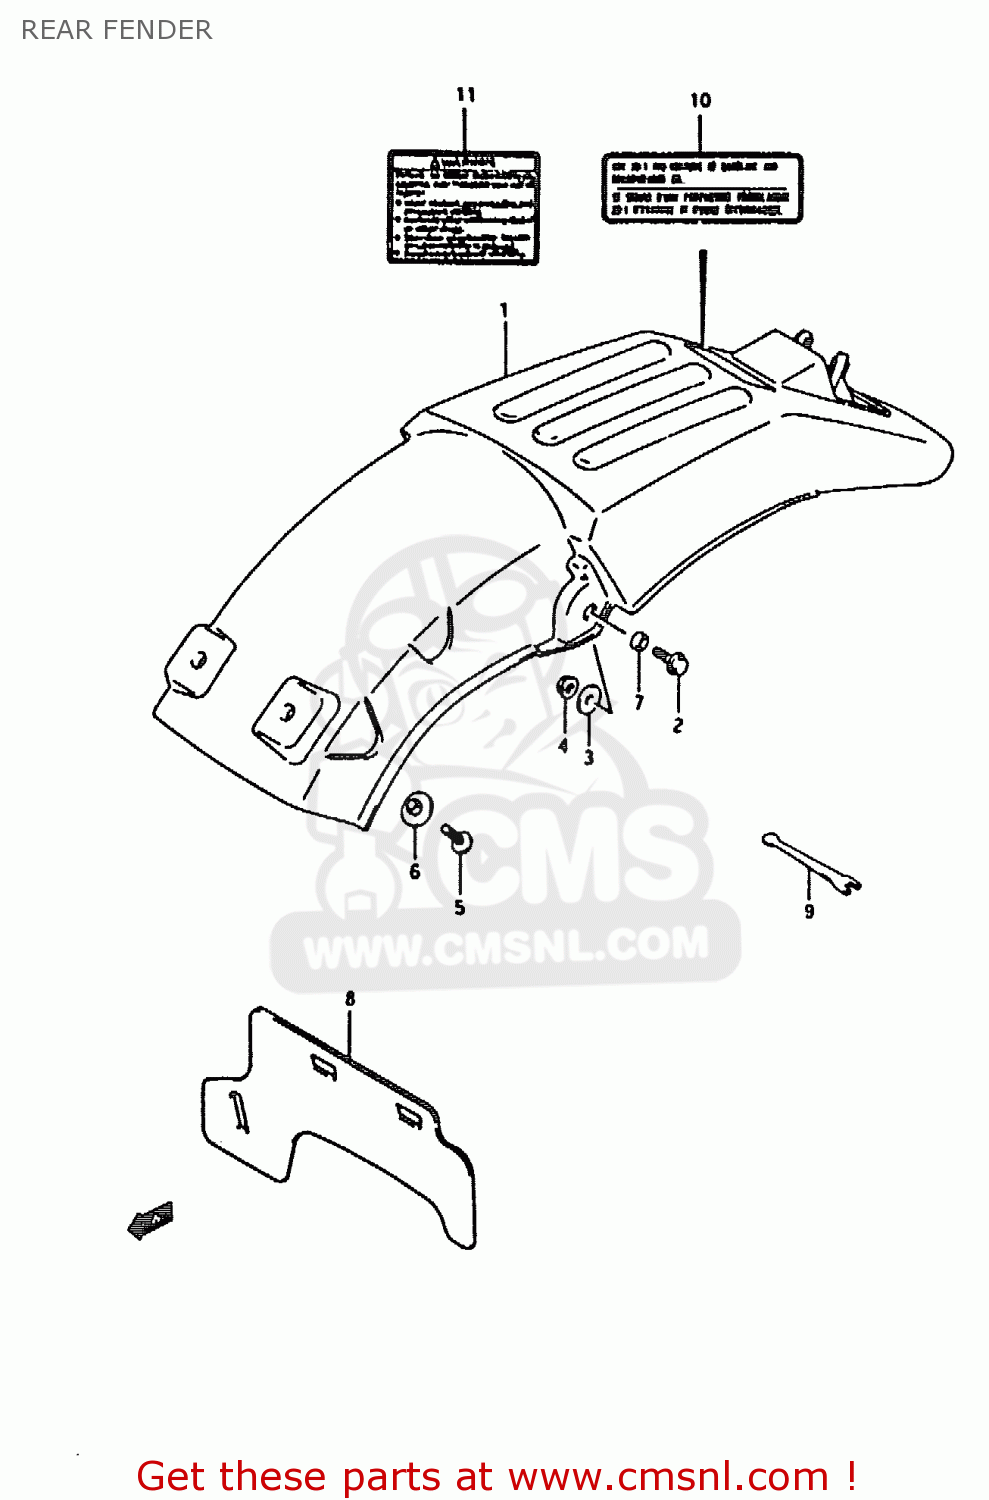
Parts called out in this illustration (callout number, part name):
1	BODY,RR FENDER
2	BOLT
3	WASHER(8.5X20X1.6)
4	NUT
5	SCREW
6	WASHER
7	SPACER (8.8X12X4)
8	MUDGUARD,RR FENDER
9	SPANNER,OPEN
10	LABEL,WARNING
11	LABEL
12	MANUAL, OWNER'S
